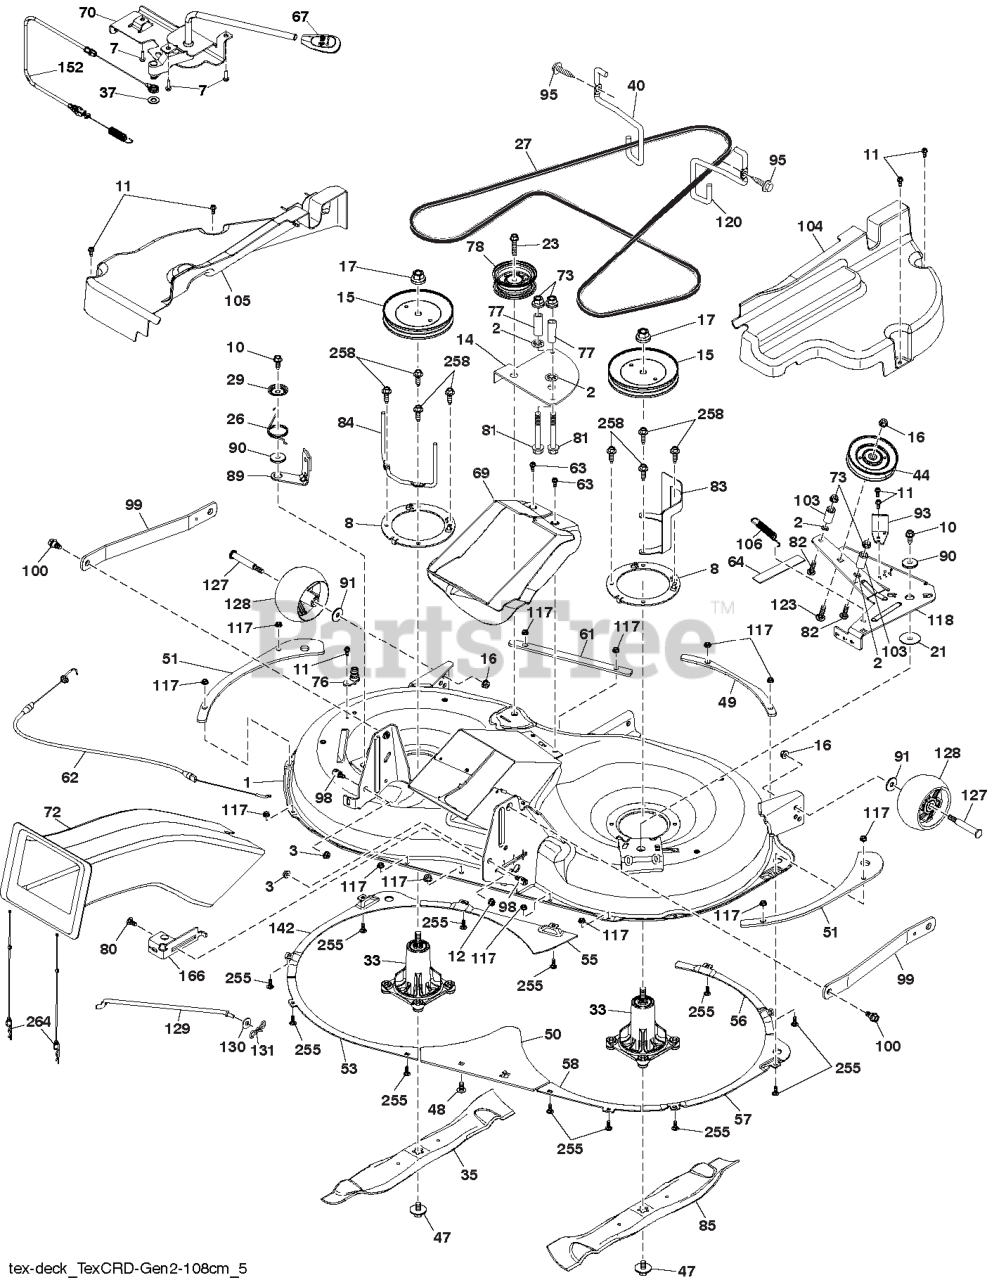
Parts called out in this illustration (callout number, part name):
1	Decks
2	PALNUT 1/4
3	GSPW Nuts
10	SCREW 3/8-16X1
11	SCREW.1/4-20X5/8
12	NUT HEXAGON FLANGE 5/16-18 ST
15	PULLEY.MANDREL.5.438.P
16	NUT LOCK FLG 3/8-16 UNC
21	WASHER, WEAR LT (1 2)
23	BOLT;HEX_3/8-16 X 1.78.CLRZINC
26	SPRING.TORSION.BRAKE
29	SRPING.TORSION.RETAINE
37	WASHER
44	PULLEY.V.IDLER
47	SCREW.SEMS.7/16-20X1.HEX.HEAD
63	HEX.WASHER.HEAD 1/4-20 X .65
64	VIBRATION PAD
67	HANDLE.CLUTCH.CABLE.LT
70	CLUTCH.ASM.MANUAL.YT.PREDATORQ
73	NUT FLG, NYLOCK, 1/4-20 GR G C
76	PORT.WASHOUT
77	SPACER.KEEPER
78	PULLEY.IDLER.48"PRIMARY
80	GSPW Bolts
81	BOLT.HEX.FINISHED.1/4-20
82	BOLT.RDHD.SHRT.NK.1/4-20X1-1/2
84	KEEPER.BLT.PNT.MNDRL.PULL.6.25
89	BRAKE.LEVER.ASM
90	SPACER.RETAINER
93	RP ARM.BRAKE.MOWER.38"LH.TEX
95	SCREW, 3/8-16X3/4
98	STUD.W/"D"ANTI-ROTATION
100	BOLT.SHOULDER
117	NUT T
123	GSPW Bolts
128	WHEEL.GAUGE.RALLY
129	ROD ROD. SWAY CRD GEN II
131	PIN.COTTER.5/16.BOW TI
255	BOLT CUP HEAD SQUARE NECK BOLT
258	BOLT.HEX.WASHR.HED.313-18X1.19
